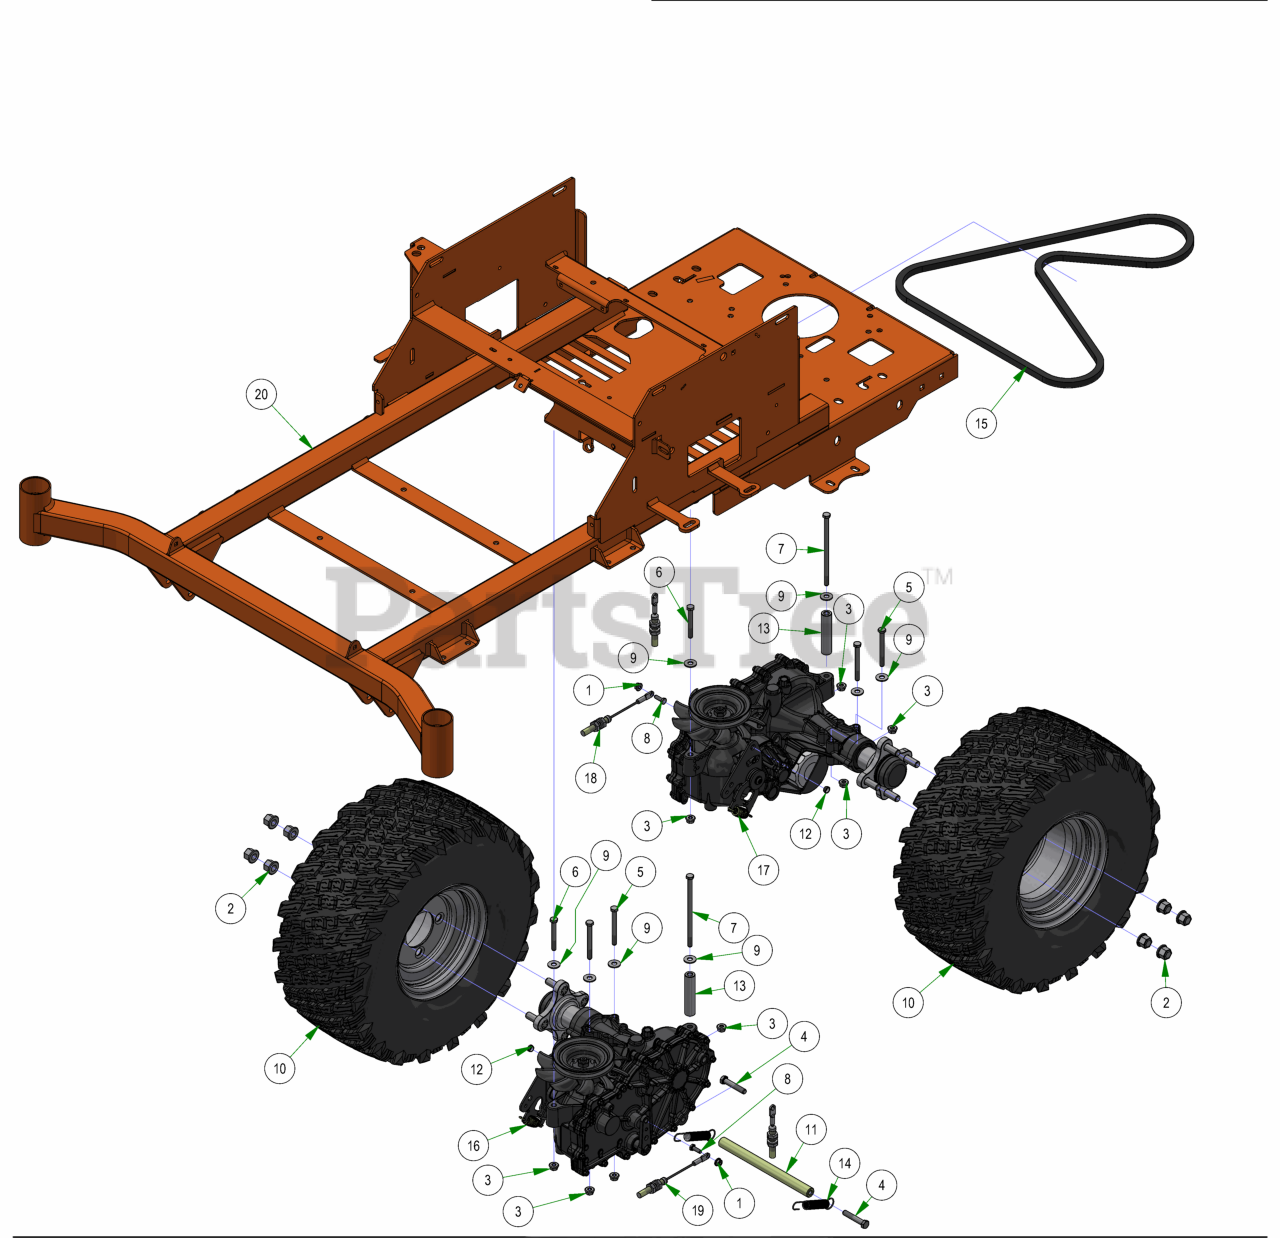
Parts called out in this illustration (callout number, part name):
1	1/4-20 NYL INSERT FLANGE LOCKNUT ZINC
2	Acorn Lug Nut
3	5/16-18 NYLON INSERT FLANGE LOCKNUT ZINC
4	3/8-16 X 2 HEX CAP SCREW (GR.5) ZINC
5	5/16-18 X 3 HEX CAP SCREW (GR.5) ZINC
6	5/16-18 X 2-1/2 HEX CAP SCREW (GR.5) ZINC
7	5/16-18 X 6 HEX CAP SCREW (GR.5) ZINC
8	1/4-20 X 3/4 HEX CAP SCREW (GR.5) ZINC
9	5/16 USS FLAT WASHER (7/8 OD) ZINC
10	20 x 10-8 Reaper Assy.
11	2017 Transaxle Spacer-ZT
12	Drive Arm Transaxle Spacer
13	2017 Transaxle Spacer
14	Brake Return Spring
16	2021 RH 2800 Transaxle
17	2021 LH 2800 Transaxle
18	2021 Load Balanced Brake Cable 1
19	2021 Load Balanced Brake Cable 2
20	2025 MZ-Avenger 54-60 Frame
